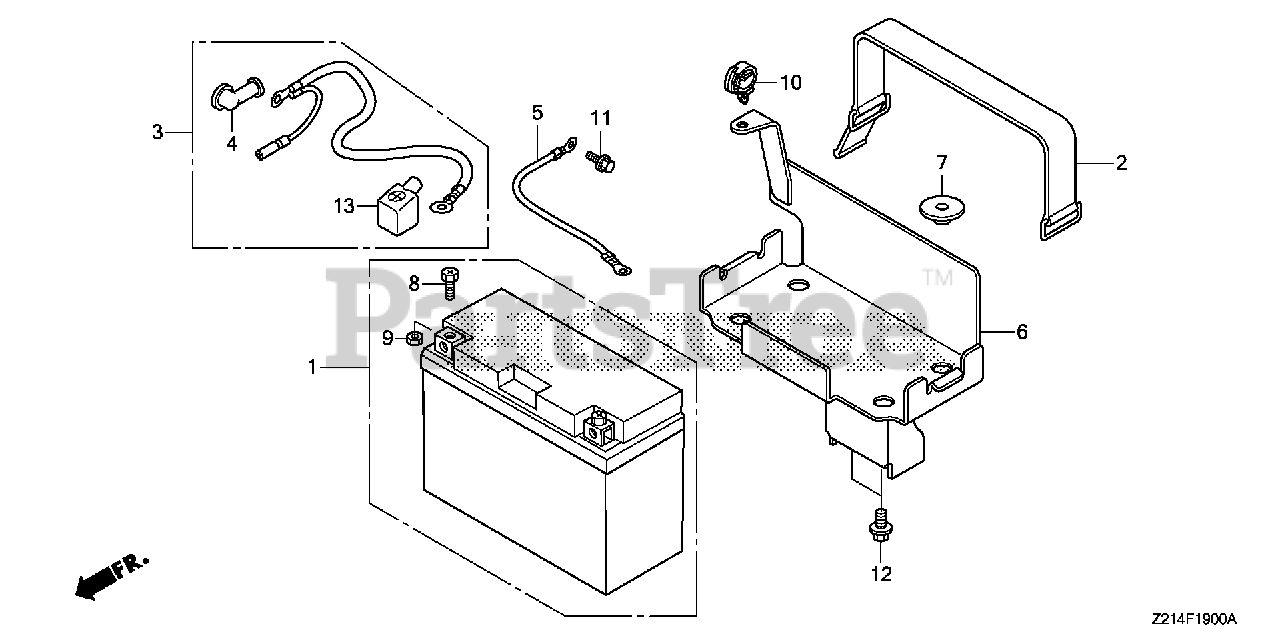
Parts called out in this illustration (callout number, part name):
1	BATTERY (YTZ14S) (YUASA) (MSDS)
2	BAND, BATTERY
3	CABLE ASSY., STARTING
4	COVER, STARTER MOTOR TERMINAL
5	CABLE ASSY., GROUND
6	PLATE, BATTERY *NH105* (MAT BLACK)
7	RUBBER, BATTERY BOX
8	BOLT, BATTERY TERMINAL
9	NUT, BATTERY TERMINAL
10	CLIP (20MM)
11	BOLT, FLANGE (6X12)
12	BOLT, FLANGE (8X12)
13	COVER, BATTERY TERMINAL
